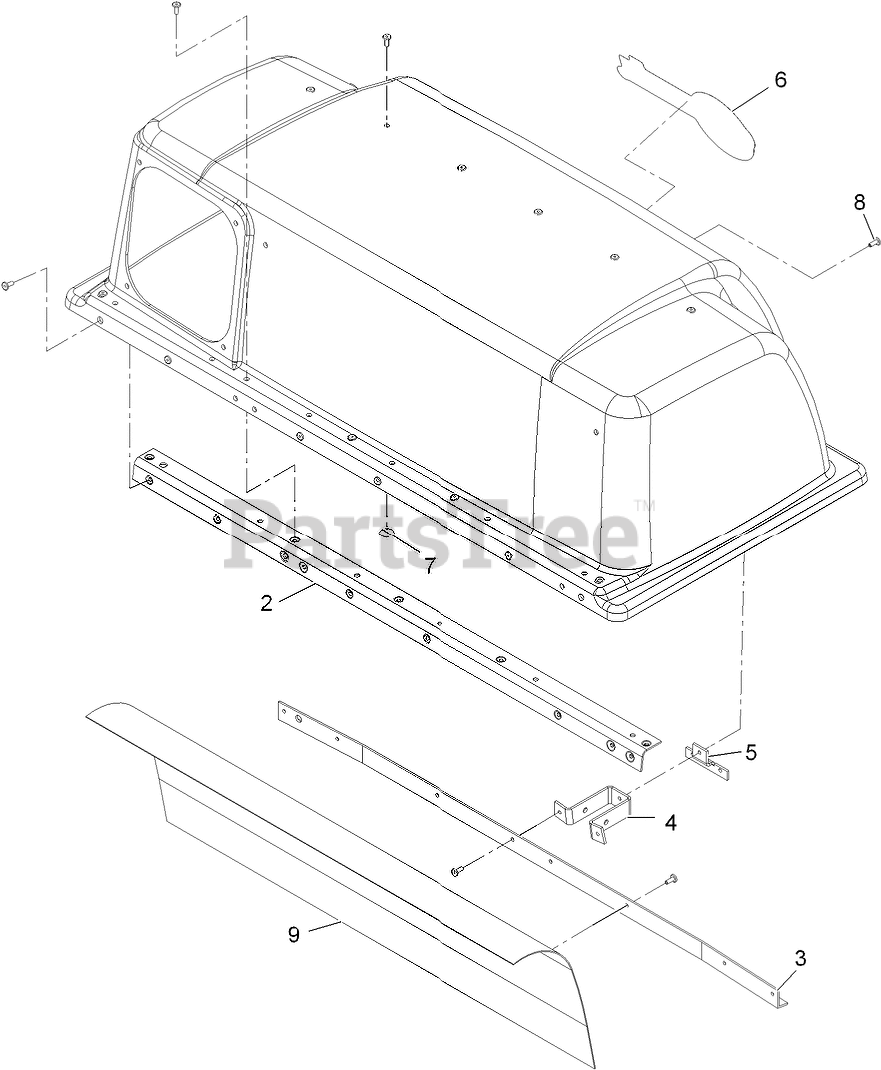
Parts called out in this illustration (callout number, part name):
2	STIFFENER-BAGGER, TOP
3	SUPPORT-SCREEN
4	ANCHOR-LATCH
5	REINFORCEMENT-LATCH
6	DECAL-EXMARK LOGO
7	WASHER-FLAT
8	RIVET-BLIND
9	SCREEN-BAGGER
